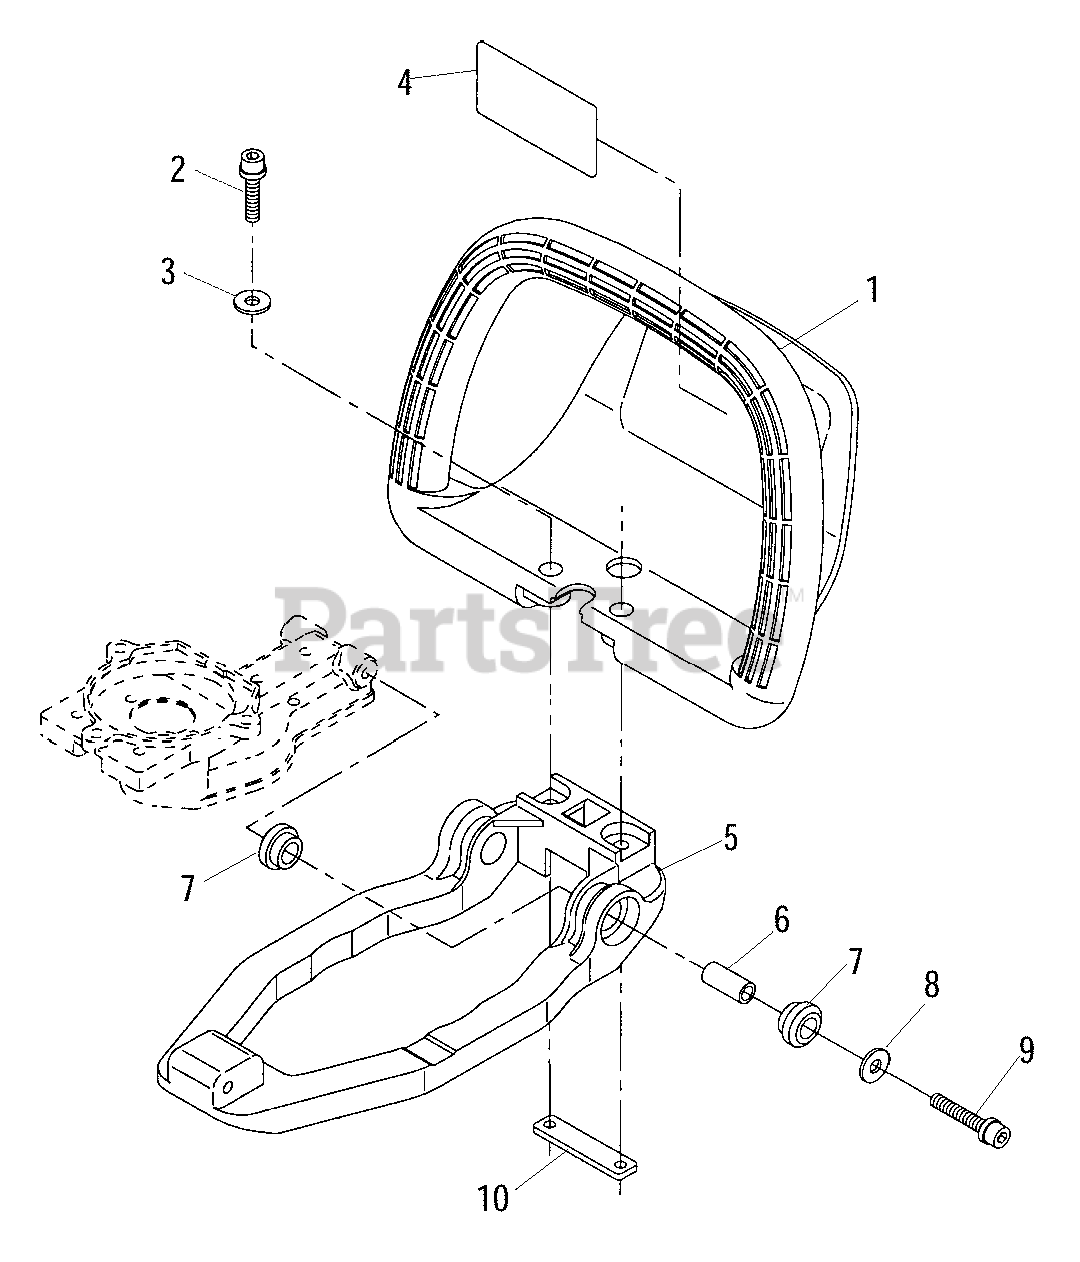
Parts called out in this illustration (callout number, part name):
1	HANDLE - FRONT
2	SCREW - 6X25
3	WASHER - 16
4	LABEL - CAUTION
5	BASE
6	COLLAR - 6
7	CUSHION
8	WASHER - 16
9	SCREW - 6X35
